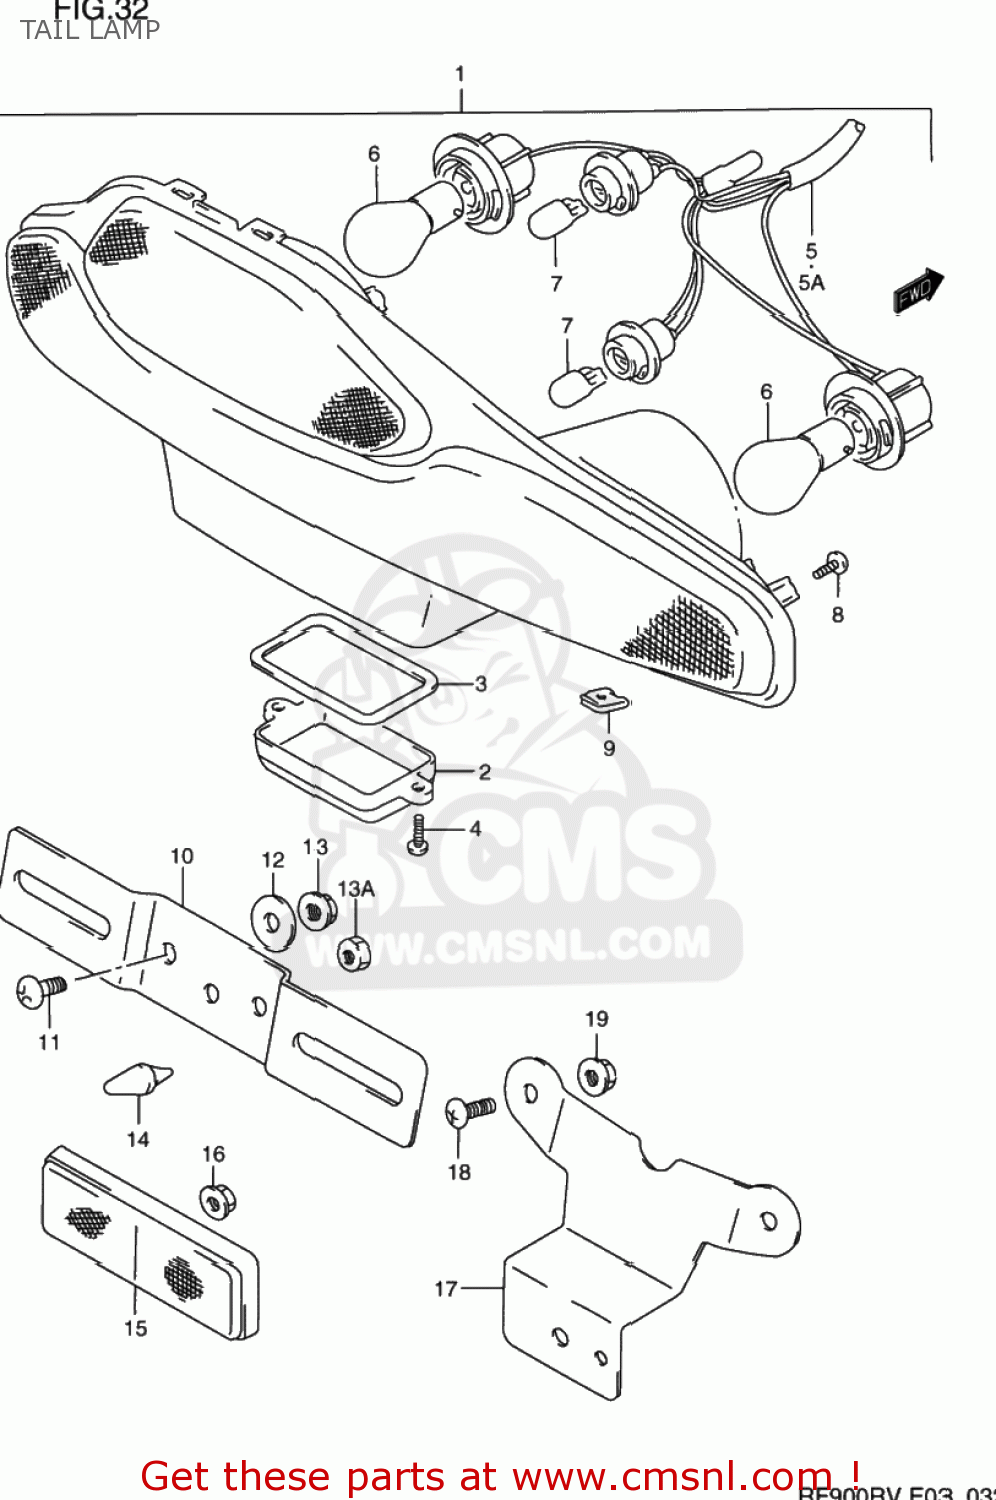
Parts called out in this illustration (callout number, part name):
1	LAMP ASSY,RR COMBINATION
2	LENS,LICENSE LAMP
3	GASKET (NAS)
4	SCREW
5	SOCKET ASSEMBLY
5A	SOCKET & CORD
6	BULB(12V21W)
7	BULB(12V5W)
8	TPG SCREW
9	NUT
10	BRACKET,LICENSE PLATE
11	SCREW
12	WASHER(6.5X20X1.6)
13	NUT 6MM
13A	NUT
14	CUSHION
15	REFLECTOR ASSY,RR
16	NUT
17	BRACKET,RR REFLECTOR
18	SCREW 6X12
19	NUT
